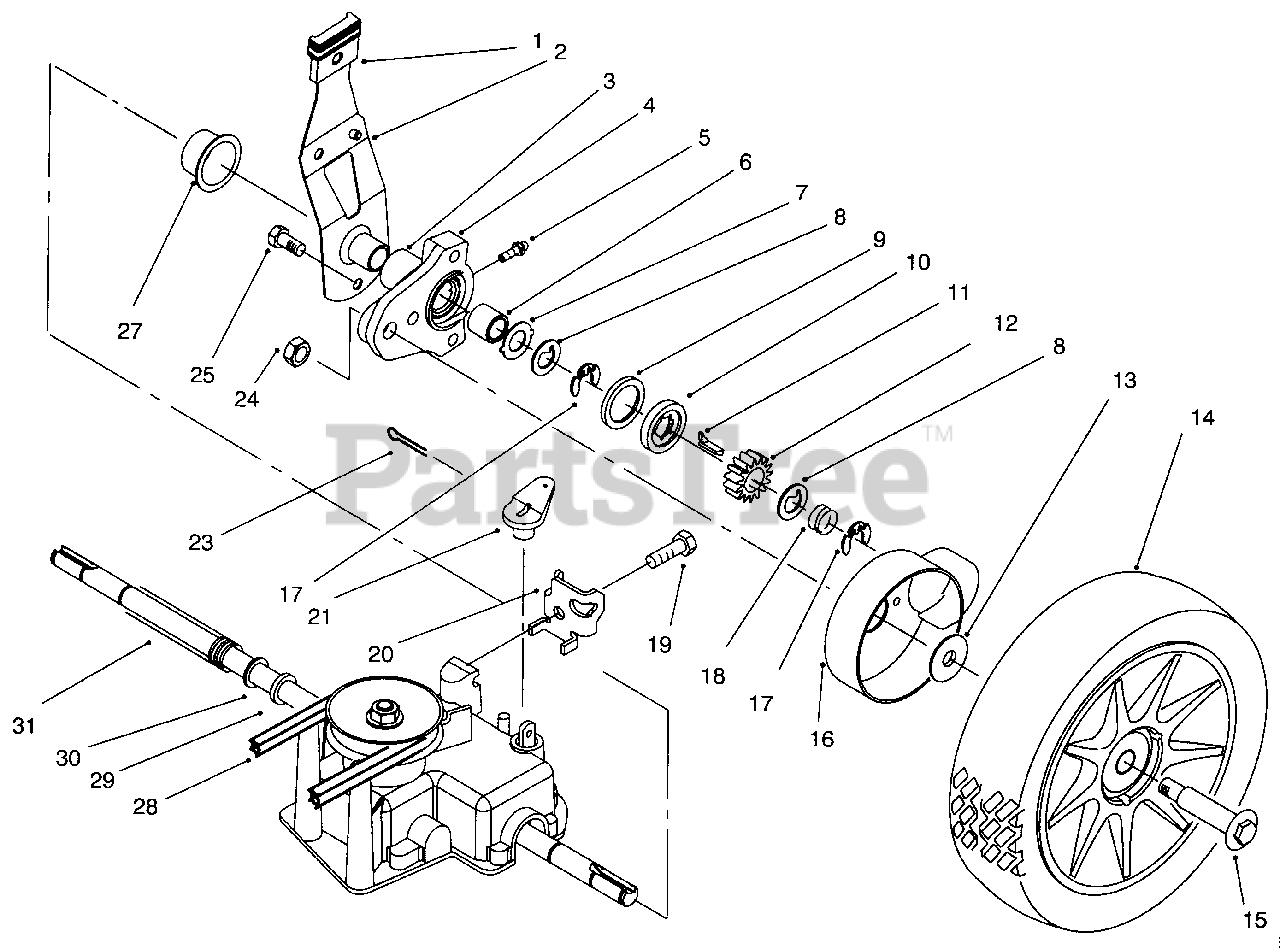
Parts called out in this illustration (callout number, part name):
1	Knob-Spring Arm (Ref.)
2	Spring Arm Assy L. H.
4	Pivot Arm Assembly (Incl. Ref. #3, 5, & 6)
5	Fitting-Grease (Ref.)
7	Washer-Thrust
8	Washer-Thrust
9	Ring-Friction
10	Washer-Clutch
11	Key-Rocking, L. H.
12	Gear-Pinion
13	Washer-Stepped
14	Wheel-8"
15	Bolt-Wheel
16	Cover-Wheel
17	Ring-Retaining
18	Spring-Compression
19	Screw-Hex. Hd.
20	Retainer-Cable
21	Lever-Shift
23	Pin-Cotter
29	Washer-Felt
30	Washer-Flat
31	Cover-Drive Shaft
